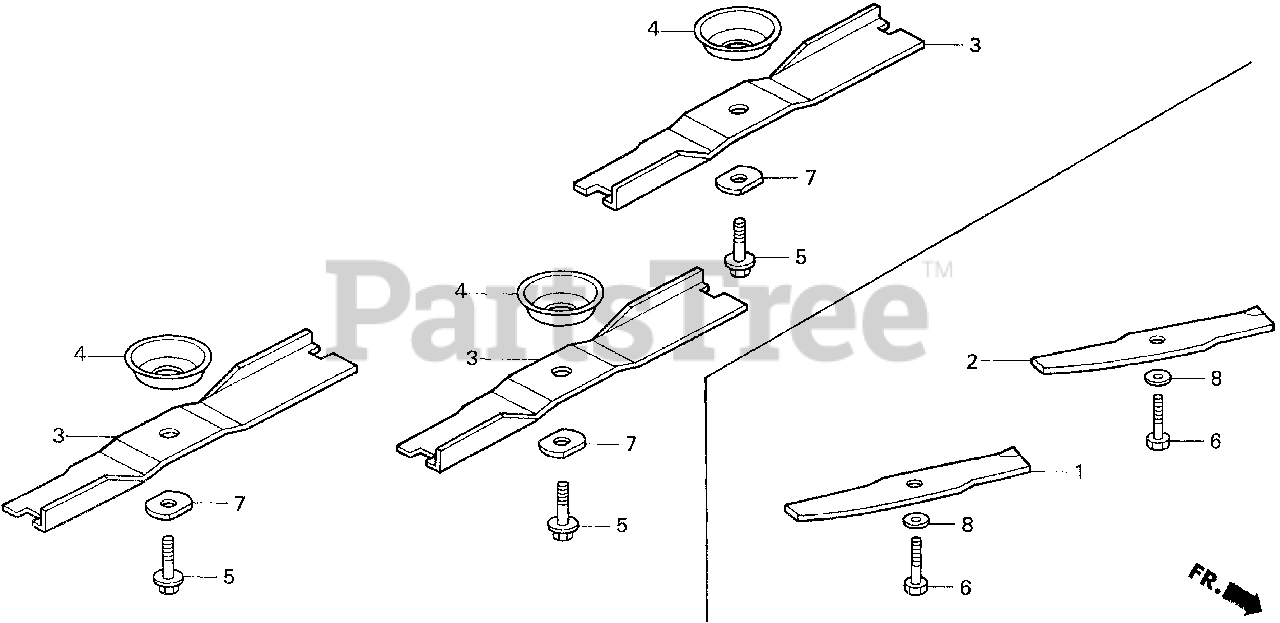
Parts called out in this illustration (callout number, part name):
3	BLADE, ROTARY
4	DEFLECTOR (LOWER)
5	BOLT, BLADE
7	WASHER, BLADE
